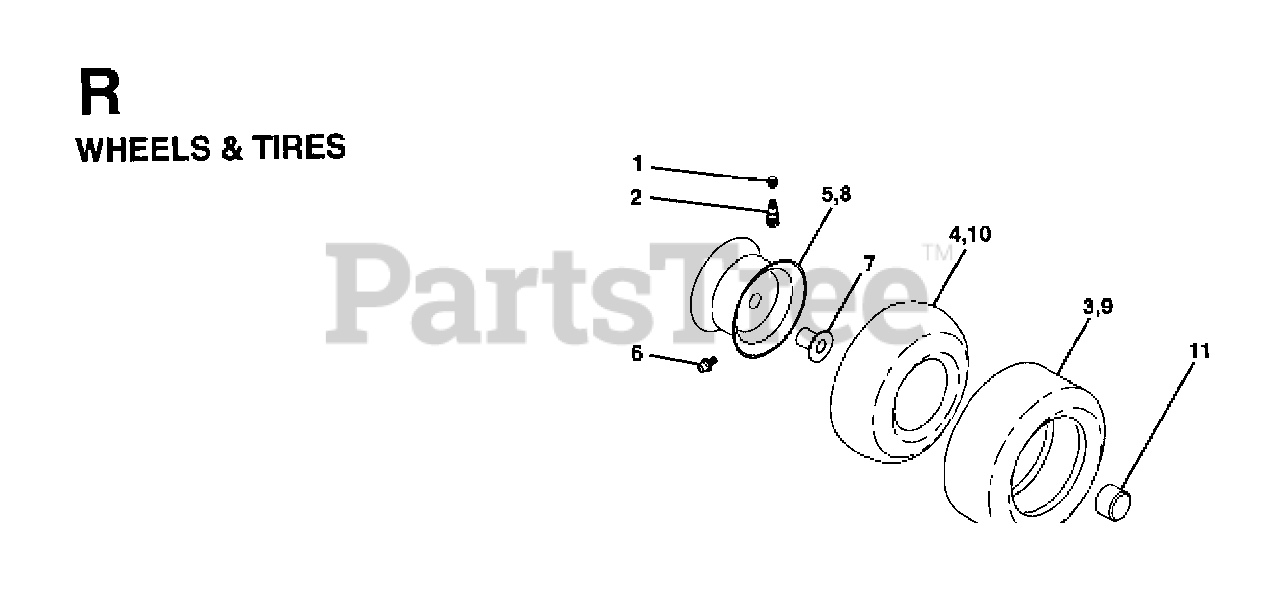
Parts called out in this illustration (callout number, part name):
1	VALVE CAP
2	VALVE STEM LT
3	TIRE HEAVY DUTY
4	TUBE.5.3/4.5/6
5	RIM ASM 6" FRONT SILVER
6	FITTING LT
7	BEARING T
8	RIM ASM 8" REAR SILVER
9	TIRE.TS.20X10-8
10	TUBE
11	CAP-HUB FRONT LT
